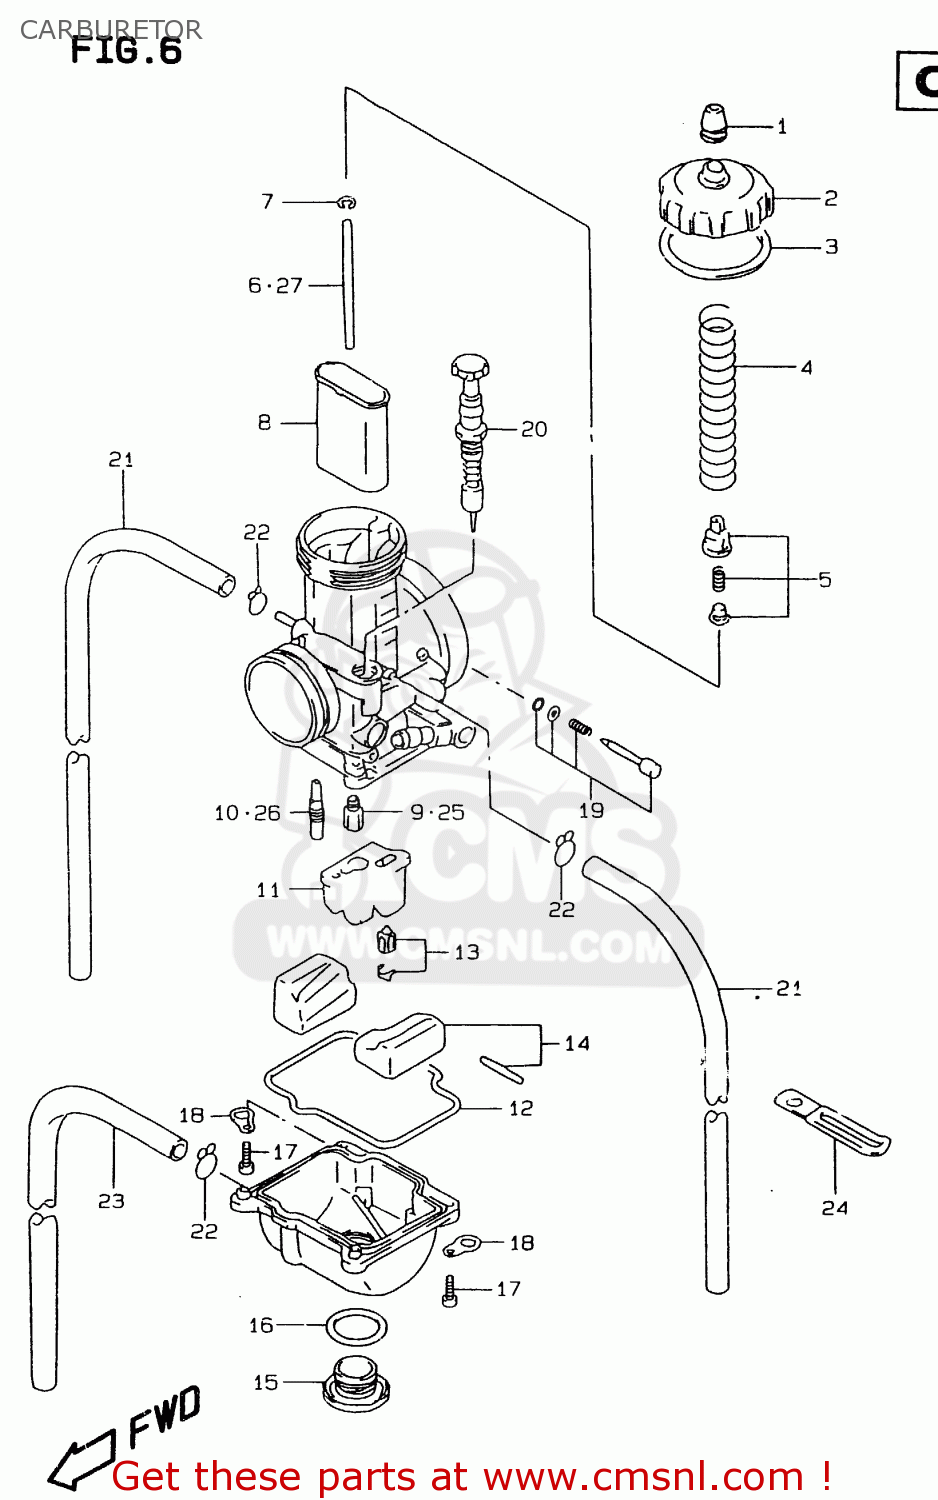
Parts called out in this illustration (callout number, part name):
1	CAP,CARBURETOR
2	CAP,TOP
3	GASKET,TOP CAP
4	SPRING
5	HOLDER SET,CABLE
6	NEEDLE,JET(R1472M 1L)
7	CLIP,NEEDLE
8	VALVE,PISTON(CA:5.0)
9	JET,MAIN(180)
10	JET,SLOW(60)
11	HOLDER
12	GASKET,FLOAT CHAMBER
13	VALVE SET,FLOAT
14	FLOAT SET
15	BOLT,DRAIN
16	O RING
17	SCREW
18	PLATE
19	SCREW SET,AIR
20	PLUNGER ASSY
21	HOSE(4X7X620)
22	CLIP
23	HOSE(3.5X6.5X600)
24	CLAMP(L:45)
25	JET,MAIN(145)
26	JET,SLOW(50)
27	NEEDLE SET,JET
